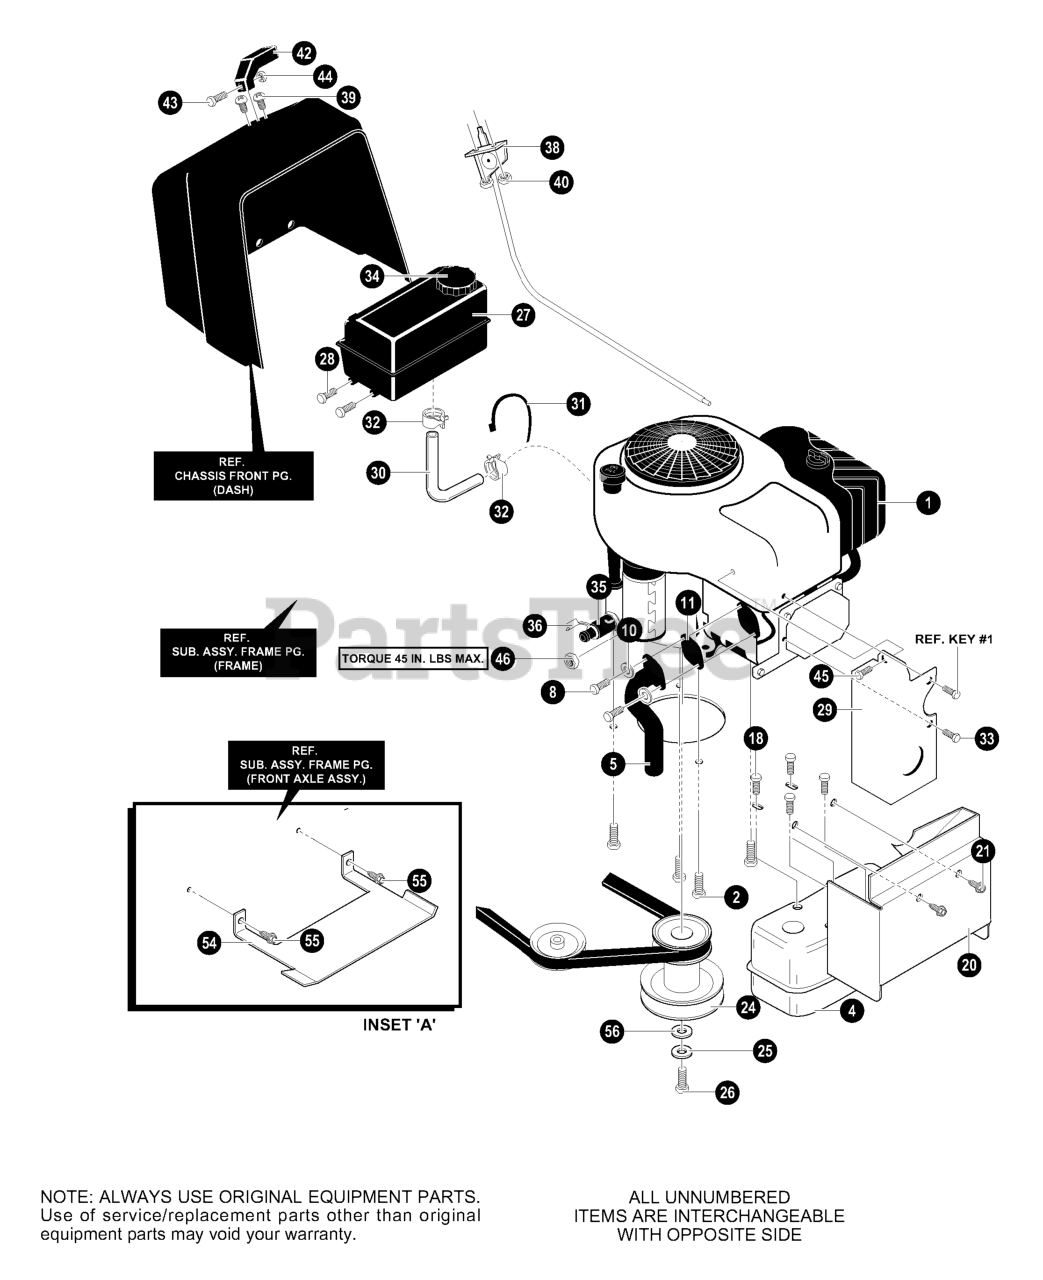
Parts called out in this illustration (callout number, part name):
1	15.5HP
2	SCREW, 3/8-16 x 1.25
4	MUFFLER, SINGLE CYLINDER
5	EXHAUST TUBE
8	SCREW, 5/16-18 x 0.75
10	WASHER, HVSPTLK
11	GASKET, Exhaust
18	SCREW, 1/4-20X .63
20	HEAT SHIELD, LOWER FRONT
21	SCREW, 5/16-18 x 0.75
24	STACK PULLEY ASSY
25	WASHER, REGSPTLK
26	SCREW, 7/16-20
27	TANK, FUEL
28	SCREW, 15TPIX
29	HEAT SHIELD SIDE
30	TUBING, .25X.50X BULK GAS
31	TIE, CABLE BLACK
32	CLAMP, FUEL CLAMP
33	SCREW, 1/4-20X.50 WAHHTAP
34	CAP,FUEL
35	OIL DRAIN VALVE ASSEMBLY
36	CAP, OIL DRAIN VALVE
38	THROTTLE CONTROL
39	SCREW, 10-24X.63
40	NUT, #10-24 HXHDNYLK
42	KNOB,THROTTLE CONTROL
43	SCREW, #8-32X .38
44	NUT, #8-32 REGHEX
45	SCREW, 10-16X.50 DRILLTITE
46	NUT, 1/4-20 REGHEXJAM
54	SHIELD, ANTI-DEHYDRATION DEFLEC
55	SCREW, 5/16-18 x 0.75 HHWATAP
56	WASHER, FLAT .480X1.00X.25
